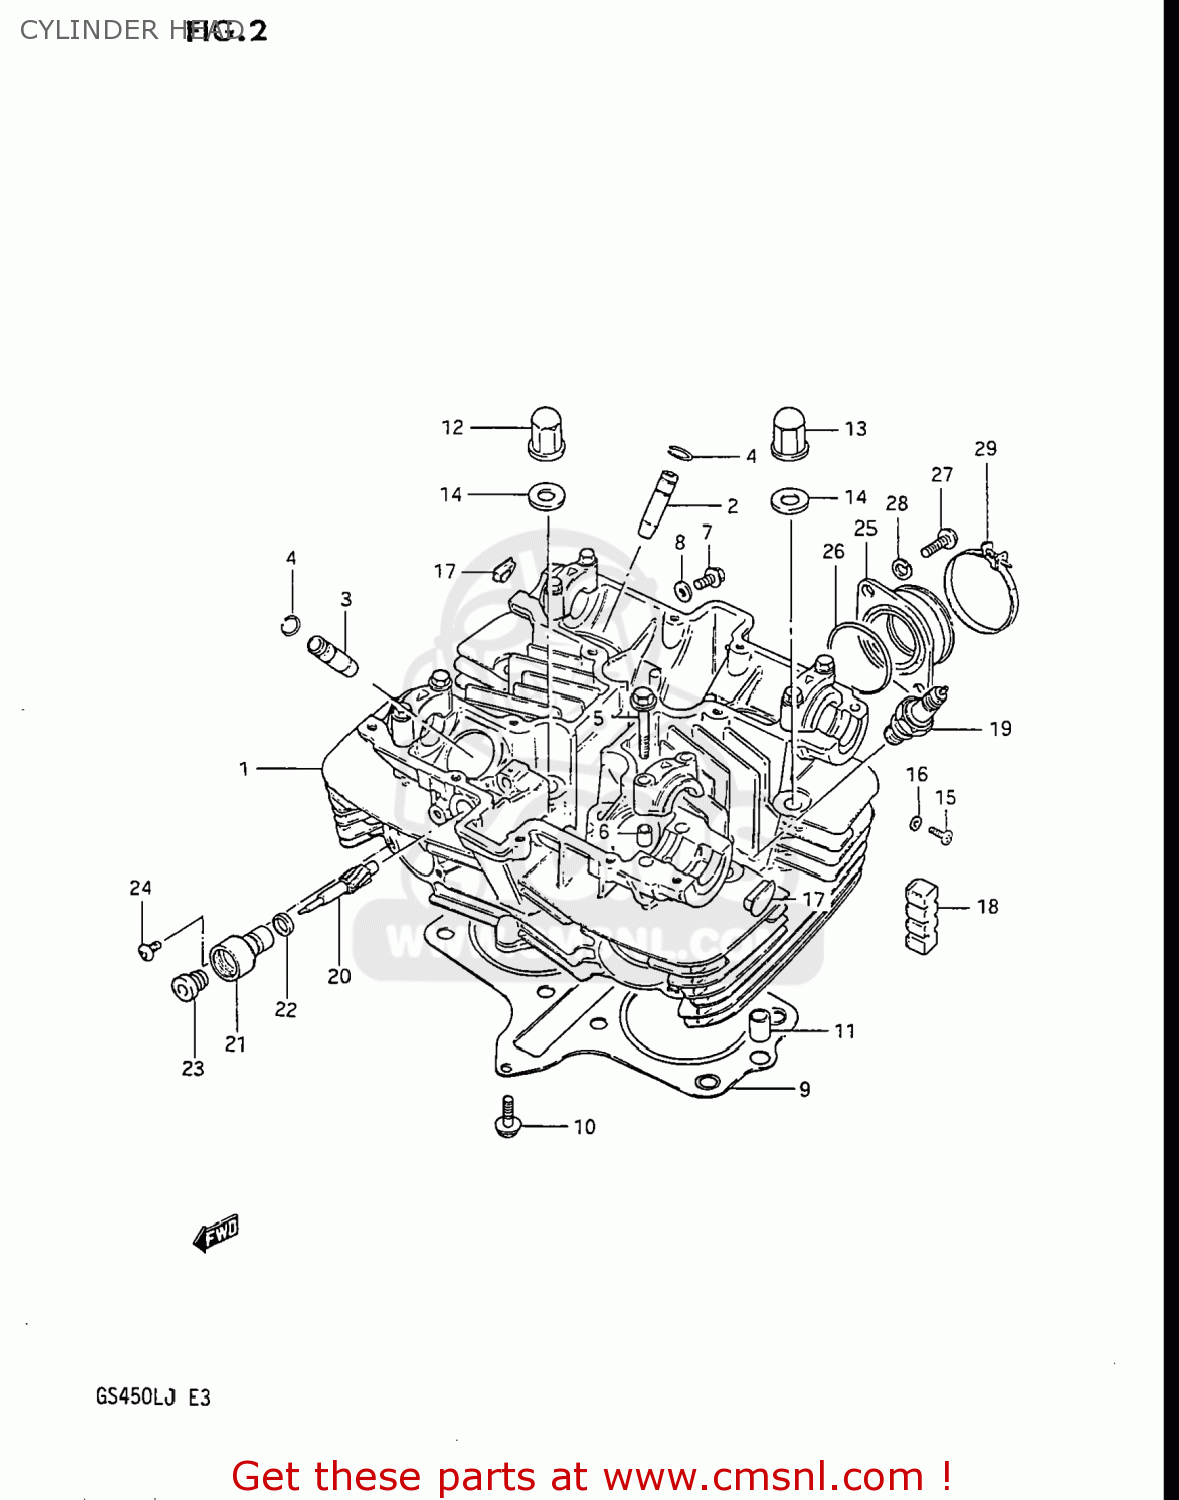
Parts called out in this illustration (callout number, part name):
1	HEAD SET,CYLINDER
2	GUIDE,INTAKE VALVE
3	GUIDE,EXHAUST VALVE
4	RING,SNAP
5	BOLT(6X39)
6	PIN(6.2X8X11)
7	BOLT
8	WASHER
9	GASKET,CYLINDER HEAD (MCA)
10	BOLT 6X30
11	PIN
12	NUT
13	NUT
14	GASKET(10.5X22X2) (NAS)
15	SCREW
16	GASKET(5.3X9.3X1.2) (NAS)
17	PLUG
18	PAD,CYLINDER
19	PLUG,SPARK
20	GEAR,TACHOMETER DRIVEN
21	SLEEVE,TACHOMETER DRIVE GEAR
22	SEAL,TACHOMETER DRIVEN
23	SEAL,OIL(5X12X8)
24	SCREW(5X12)
25	PIPE,INTAKE
26	O-RING (D:2.4 ID:39.7)
27	SCREW
28	WASHER,LOCK
29	CLAMP
